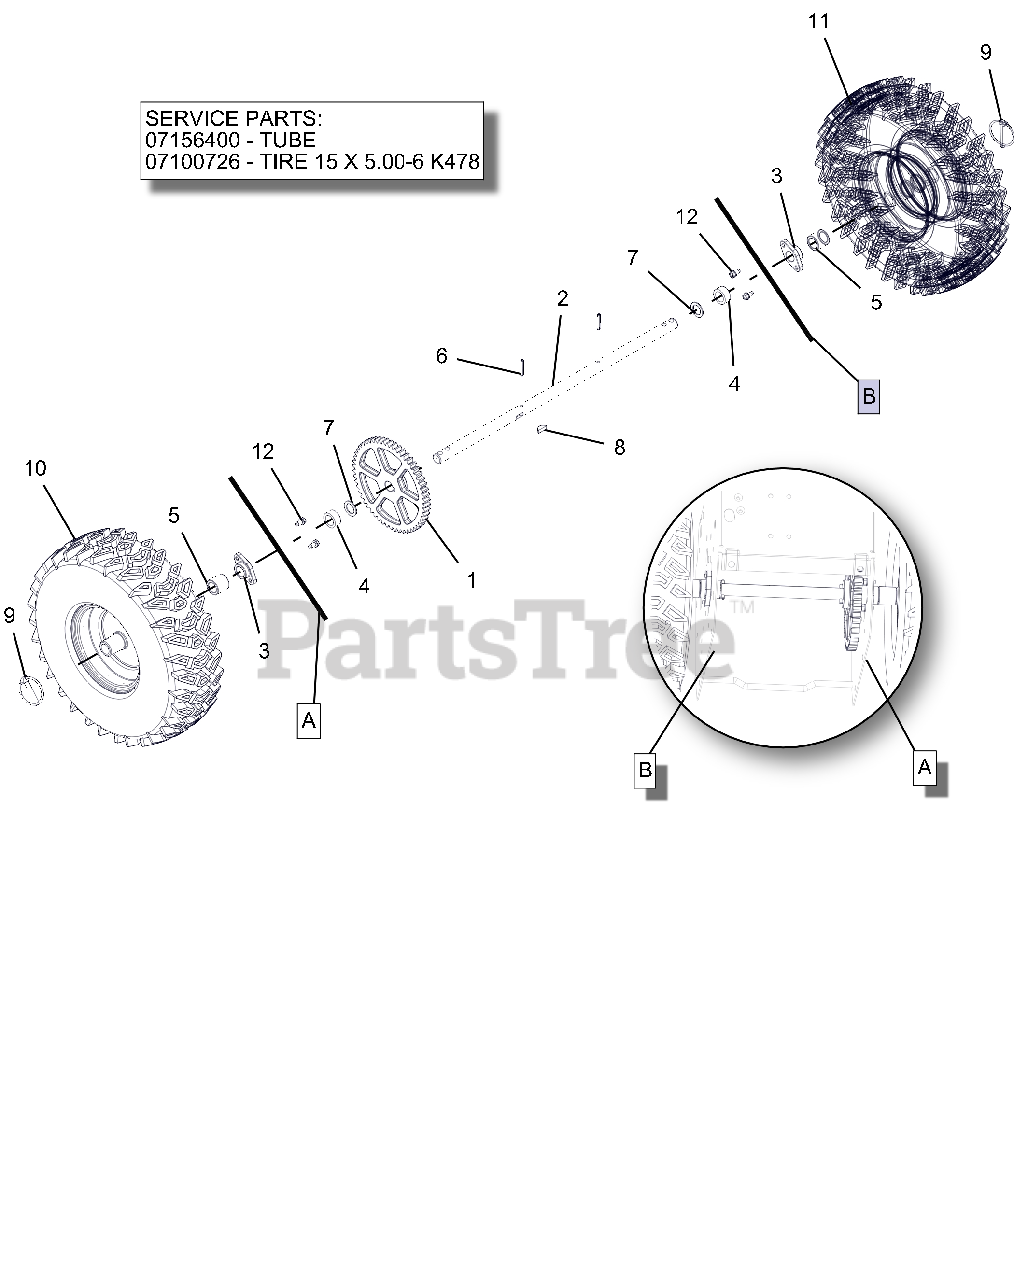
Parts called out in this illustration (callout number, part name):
1	SPUR GEAR, 54T .75ID X 6.75PD
2	AXLE, COMPACT 920,XXX 15" TIRE
3	BSHG .75X1.125X.65
4	BSHG-SLV .766 X 1.125 X .500
5	BSHG-SLV .75X1.12X1.062 NYL BK
6	PIN-ROLL .188X1.25
7	WSHR-FL-STL.754X1.125X.062YWZC
8	KEY-WDRF .25X.750X.313 SAE91
9	PIN-LOK .31X1.75
10	TIRE/WHEEL, RH 15X5.00-6 PIN
11	TIRE/WHEEL, LH 15X5.00-6 PIN
12	SCR-TAP .25-20X.50 HWH TR YWZ
13	TUBE 15 X 5.00-6
14	TIRE, 15X5.00-6 K478
